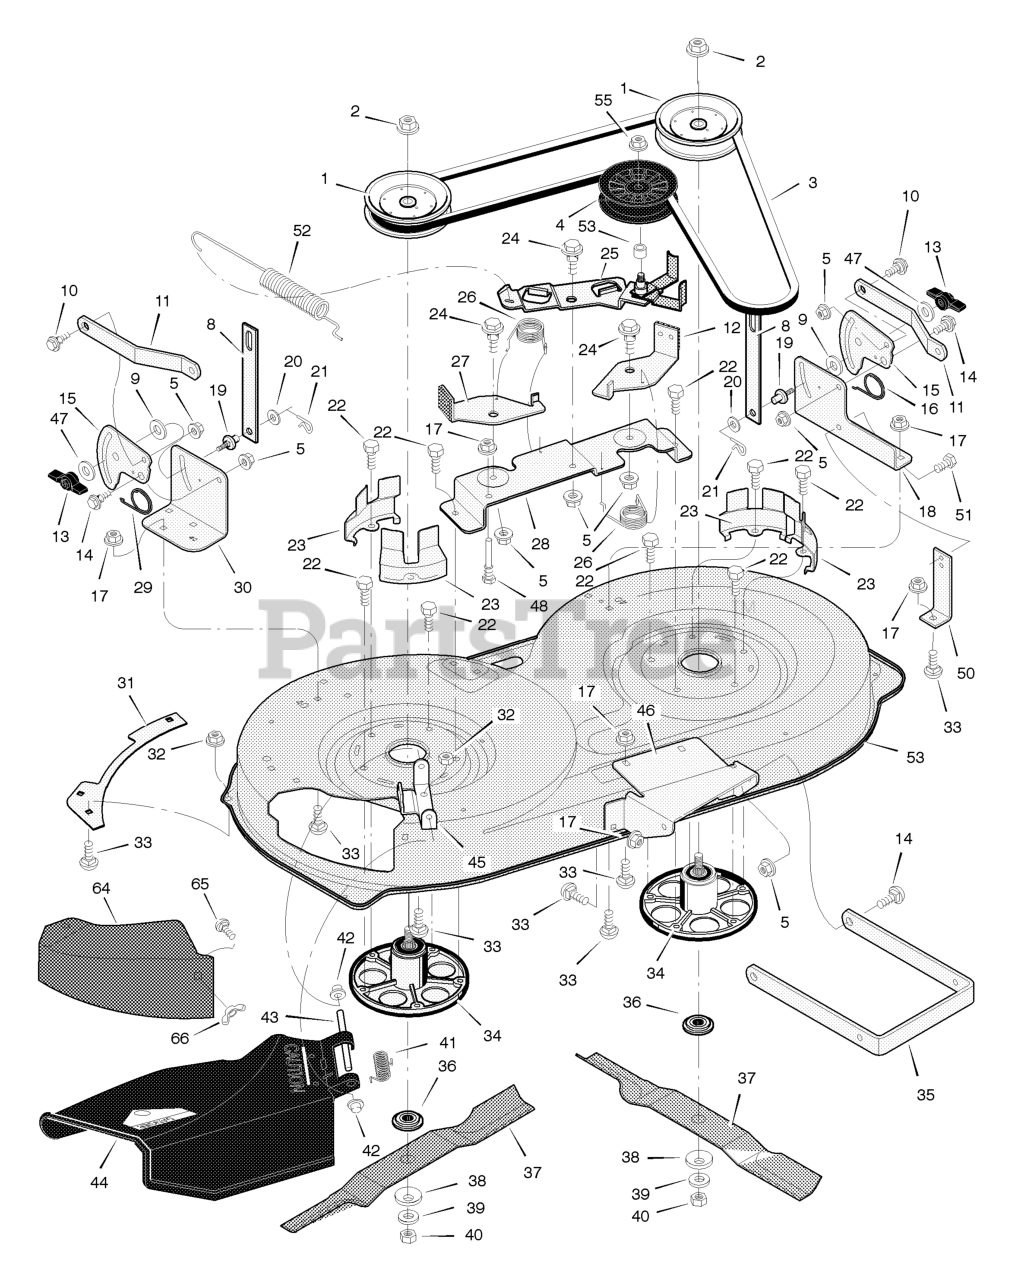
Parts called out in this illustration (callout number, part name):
1	Pulley, Jackshaft
2	Nut, Hex
3	Belt, Mower Drive
4	Pulley, Idler
5	Nut, Flange
8	Link, Lift
9	Pad, Friction
10	Bolt, Shoulder
11	Bracket, Suspension
12	Pad Assembly, Left Brake
13	Knob
14	Bolt, Shoulder
15	Plate, Suspension
17	Nut, Flange
18	Bracket, Suspension
19	Pin, Hanger
21	Pin, Cotter
22	Bolt
23	Cover, Pulley
24	Bolt, Shoulder
25	Arm, Idler
27	Pad Assembly, Right Brake
28	Bracket Assembly, Brake
30	Bracket, Suspension
31	Plate
32	Nut, Flange
33	Bolt, Carriage
34	Mandrell
35	Bracket, Suspension
36	Adapter, Blade
42	Cap, Push On
43	ROD, Deflector
44	Deflector Assembly
45	Bracket, Deflector
46	Bracket, Front Hanger
48	Guide, Belt
50	Bracket, Support
52	Spring, Extension
54	Housing, Blade
55	Nut, Flange
64	Cover, Mulch
65	Bolt
66	Wingnut
